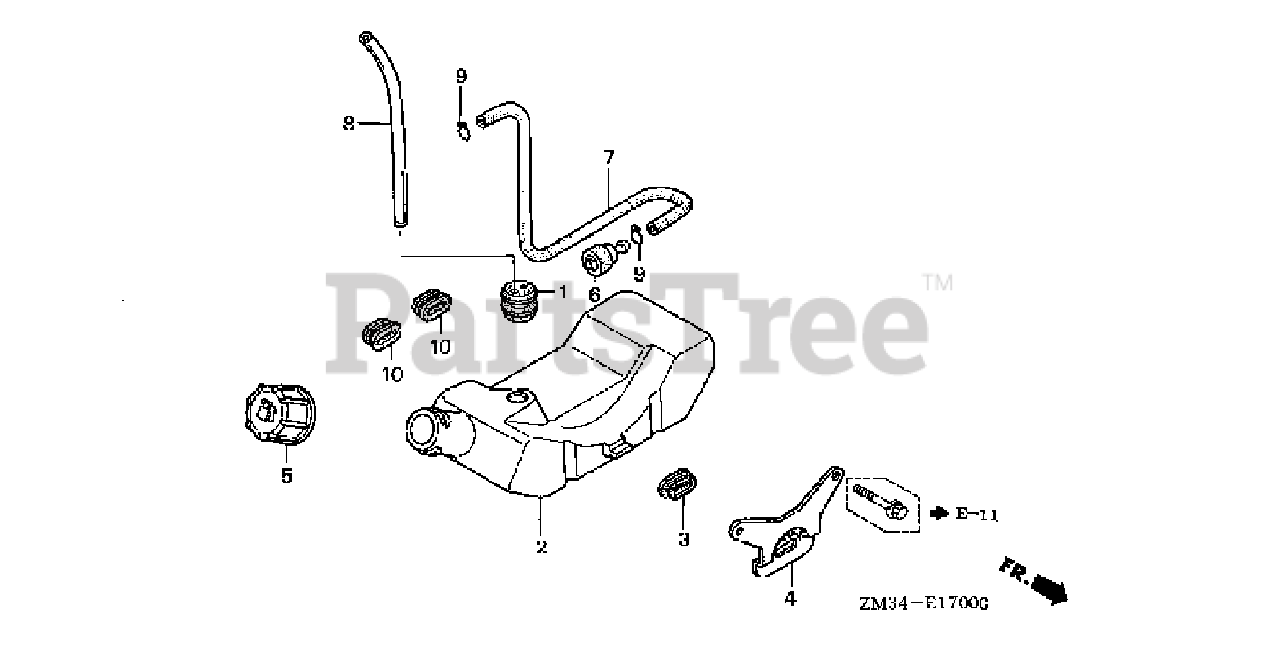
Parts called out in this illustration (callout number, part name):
1	GROMMET, FUEL TUBE
2	TANK, FUEL
3	RUBBER, TANK MOUNTING
3	RUBBER A, TANK MOUNTING
4	STAY, FUEL TANK
5	CAP ASSY., FUEL TANK
6	FILTER, FUEL
7	TUBE, FUEL
8	TUBE, FUEL RETURN
9	CLIP, TUBE
10	RUBBER, TANK MOUNTING
10	RUBBER B, TANK MOUNTING
